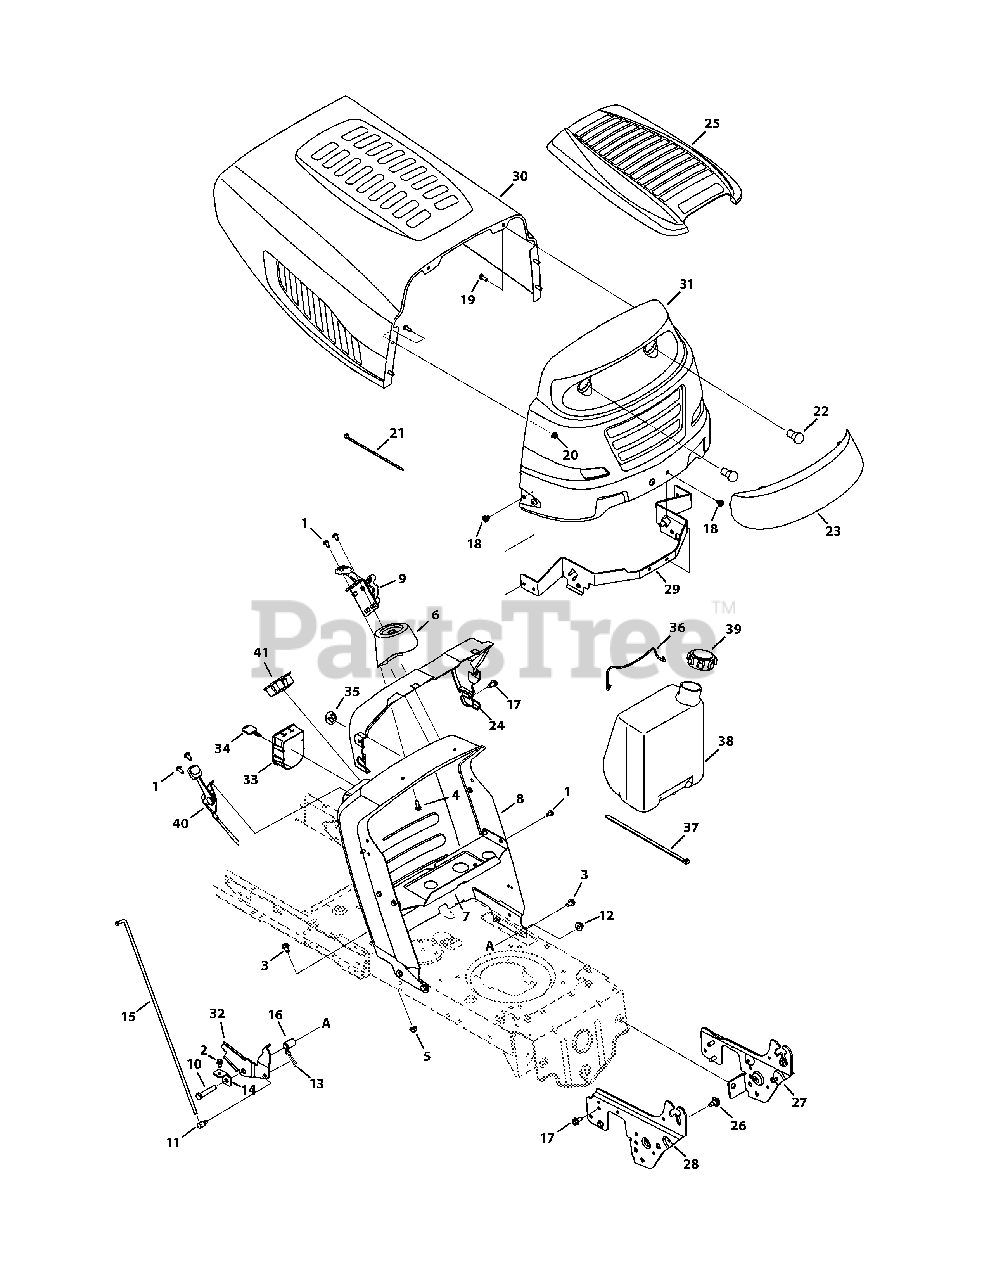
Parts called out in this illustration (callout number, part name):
1	Screw, 1/4-20 x .500
2	Hex Index Washer Screw, 1/4-20 x .500
3	Screw, 5/16-18 x .625
4	Screw, 1/4 x .750
5	Flangelock Nut, 5/16-18
6	Steering Support
7	Gas Tank Support Bracket
8	Dash, No RMC
9	7-speed Control Assembly
10	Hex Screw, 3/8-16 x 2.0
11	Ferrule, 1/4-20 x 1.0
12	Flangelock Nut, 3/8-16
13	Bow Tie Cotter Pin, 72
14	Speed Latch Tab
15	Speed Selector Control Rod
16	Flange Spacer, .390 x .671 x 1.095
17	Screw, 5/16-18 x .750
18	Screw, 5/16-18 x .375
19	Hex Screw, 1/4-20 x .620
20	Flangelock Nut, 1/4-20
21	Cable Tie
22	Miniature Lamp, 12V
23	Grill Lens
24	Dash Collar
25	Hood Cover
26	Shoulder Screw, 5/16-18, .43 x .29
29	Hood Pivot Bracket
30	Hood - Red
31	Grill - Red
32	Speed Latch, No RMC
33	Key Switch Module
35	Choke Plug
36	Battery Rod
37	Cable Tie
38	Fuel Tank, 1.5 Gallon
38	Fuel Tank, 1.36 Gallon
39	Fuel Cap
39	Fuel Cap 1.36 Gallon
40	Throttle/Choke Cable
41	Ammeter
